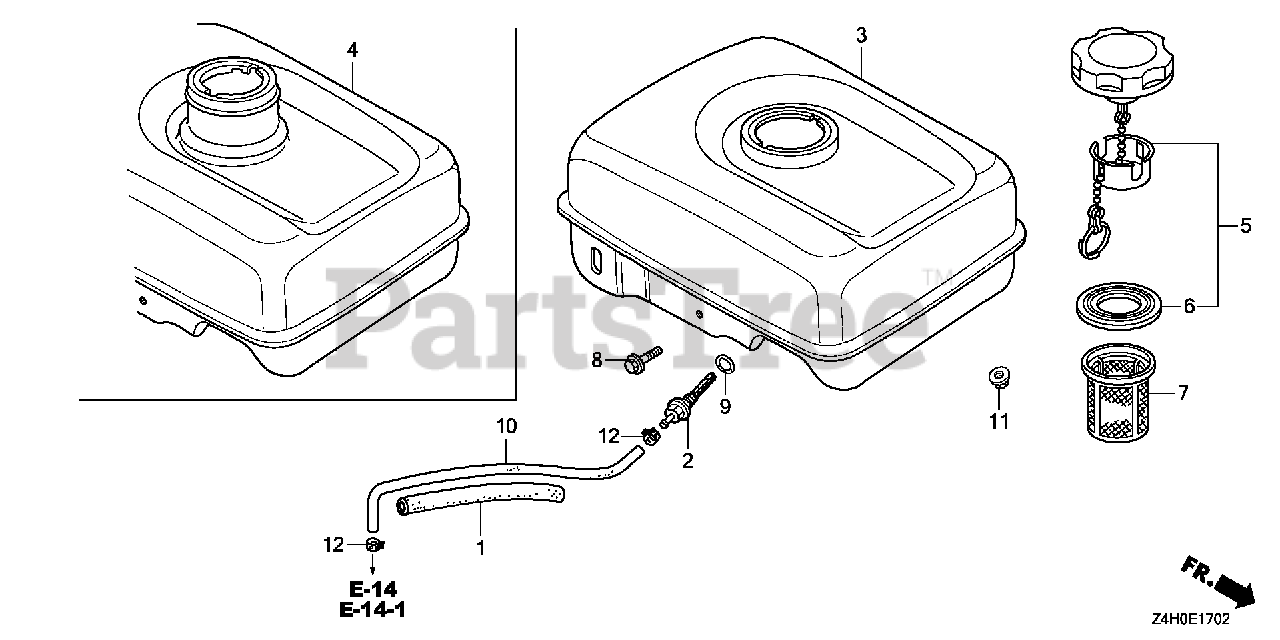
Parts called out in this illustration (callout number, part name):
1	RUBBER, SUPPORTER (107MM)
2	JOINT, FUEL TANK
3	TANK, FUEL *NH31* (GAUGELESS) (MCKINLEY WHITE)
5	CAP, FUEL FILLER
6	GASKET, FUEL FILLER CAP (39X62X3) (RADICON)
7	FILTER, FUEL
8	BOLT, FLANGE (6X29)
9	O-RING (13.5X1.5) (ARAI)
9	O-RING (14MM) (NOK)
10	TUBE, FUEL (4.5X140) (FKM)
11	NUT, FLANGE (6MM)
12	CLAMP, TUBE (D8)
